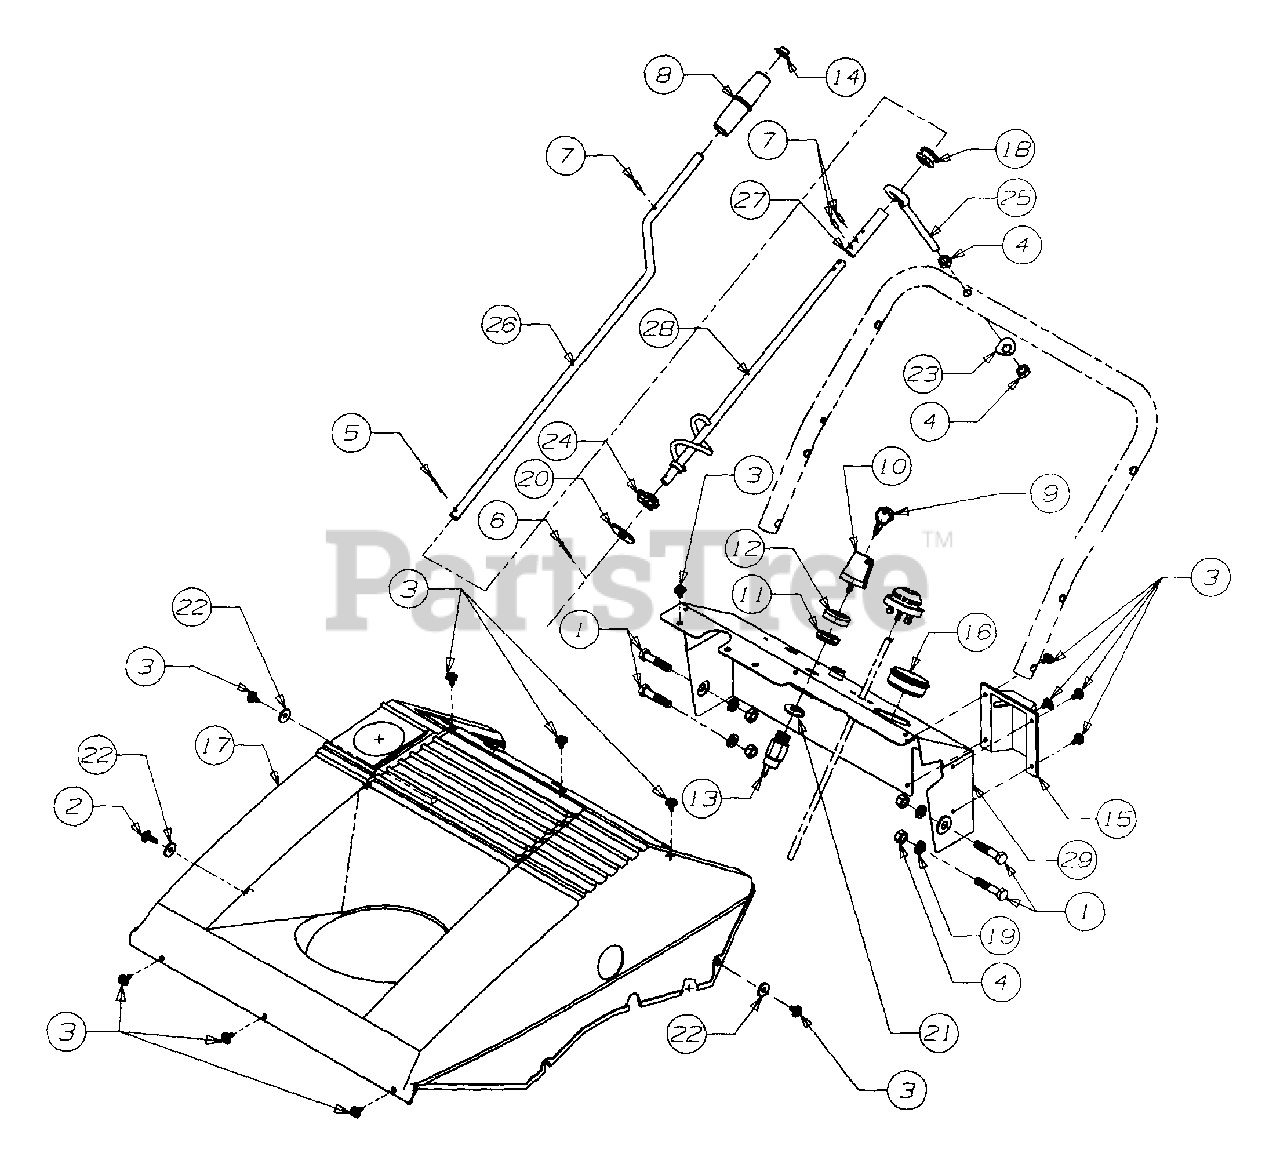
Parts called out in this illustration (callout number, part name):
1	Scr., Hex Cap 5/16-18 x 511
2	Scr., Hex B-Tapp #10-16 x .62 (152)
2	Scr., Hex B-Tapp #10-16 x .38 (E162)
3	Scr., Hex B-Tapp 010-16 x .38
4	Nut, Hex 5/16-18
5	Pin, Cotter 3/32 Dia. x 1"
6	Pin, Cotter 3/32
7	Roll, Pin 1/8 O.D. x .63 Lg.
8	Knob, Chute Crank
9	Key, Ignition
10	Key, Ignition w/o Logo
11	Nut, Ignition Key
12	Cover, Ignition Switch
13	Switch
14	Cap, Push
15	Choke Cover
16	Insert Plug
17	Shroud 4.5 HP (152)
17	Shroud 5.0 HP (E162)
18	Grommet, Rubber
19	Lock Washer 5/16" Dia.
20	Washer, Flat 3/8 x 1.25
21	Lock Washer 5/8"
22	Flat Washer .19 x .62
23	Washer, Saddle .320
24	Hex Bushing
25	Eyebolt
26	Upper Chute Crank
27	Spacer
28	Chute Crank
